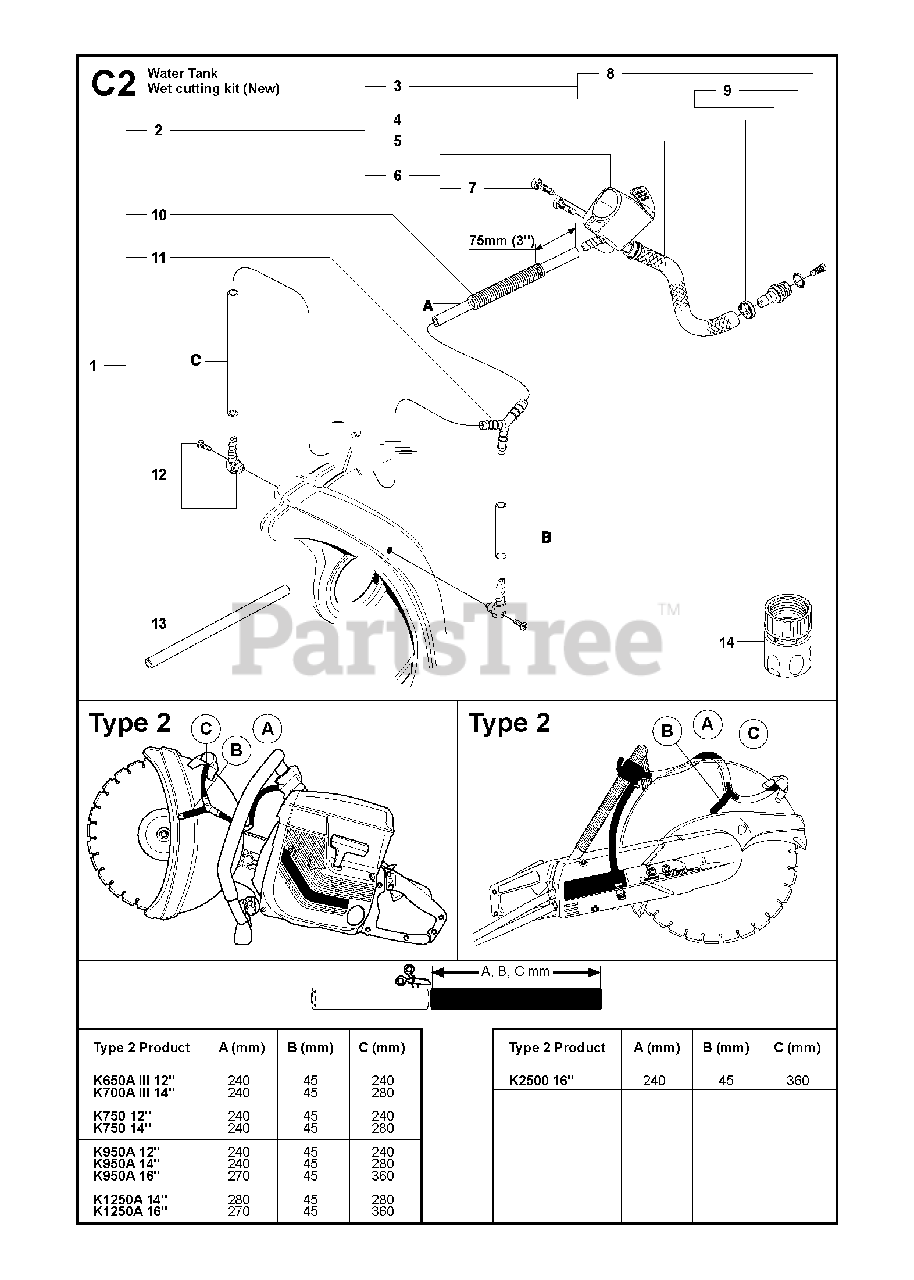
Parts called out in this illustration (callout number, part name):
1	HOSE KITK750. Incl. 2, 10 - 13
1	HOSE KITIncl. 2, 10 - 13
2	VALVE ASSYIncl. 3 - 6
2	HOSE ASSYK750. Incl. 3 - 6
3	NIPPLEIncl. 8
4	HOSE CLAMP
5	HOSEL=230mm
6	VALVE ASSYIncl. 7
6	VALVE ASSYK750. Incl. 7
7	SCREW ITXSCTK750
9	O-RING
10	PROTECTIVE SPRING
13	HOSE
14	COUPLER
